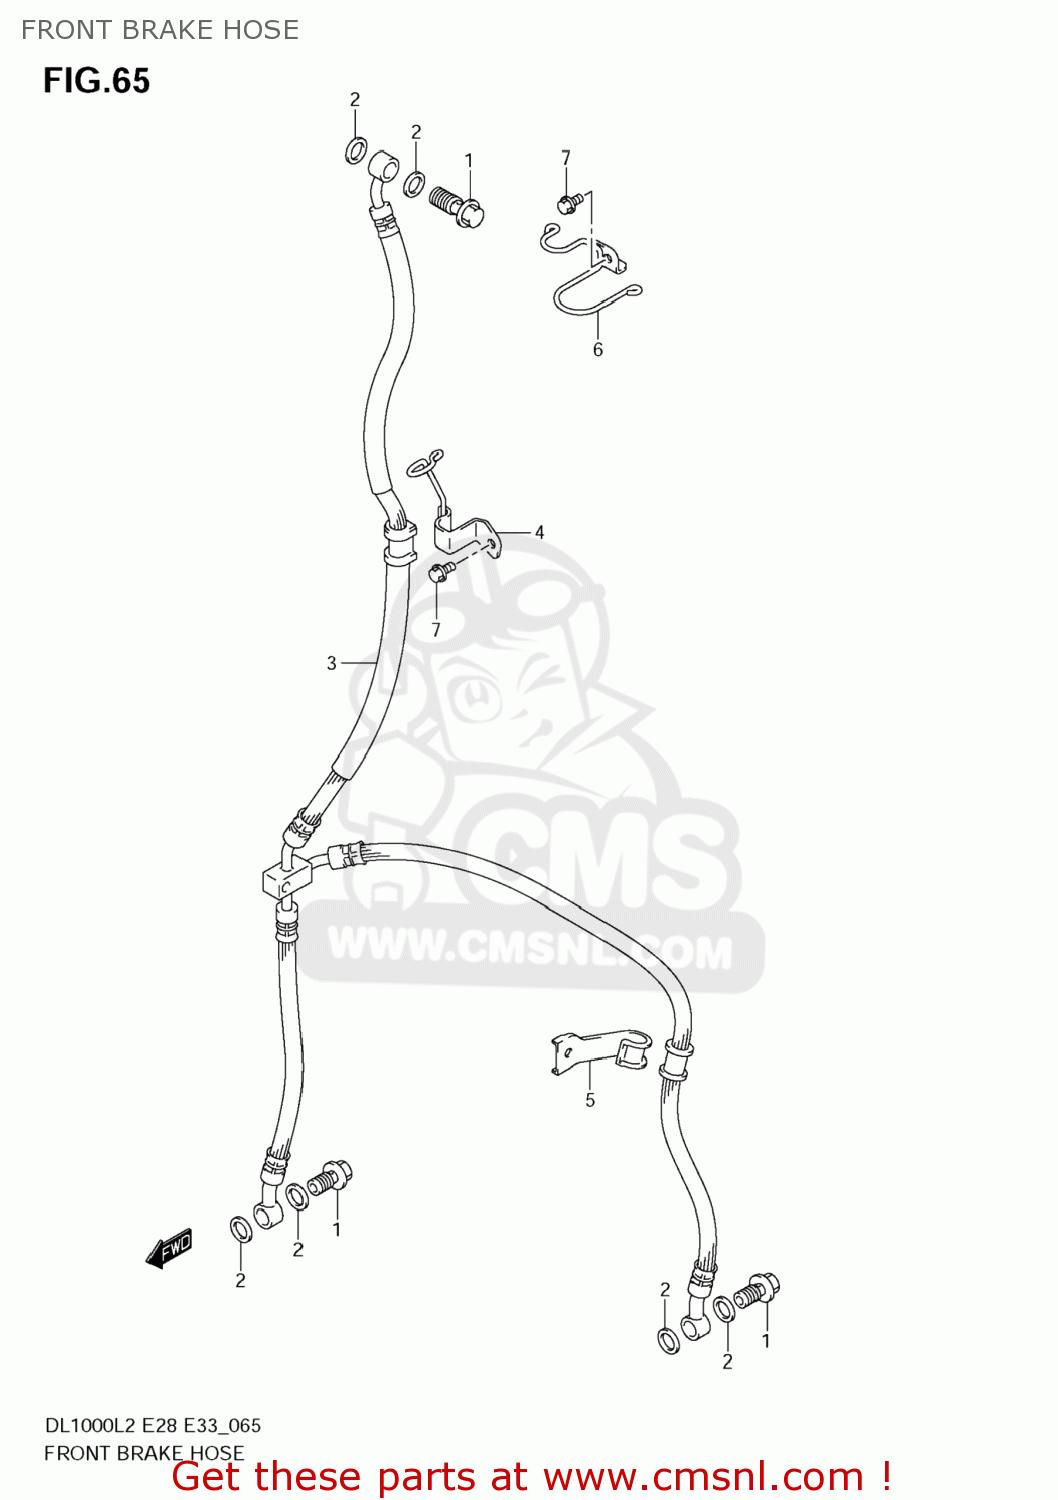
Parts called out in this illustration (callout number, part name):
1	BOLT UNION
2	WASHER(10X15X1.5)
3	HOSE,FR BRAKE
4	CLAMP,FR BRAKE HOSE
5	CLAMP,FR BRAKE HOSE
6	GUIDE,FR BRAKE HOSE
7	BOLT
